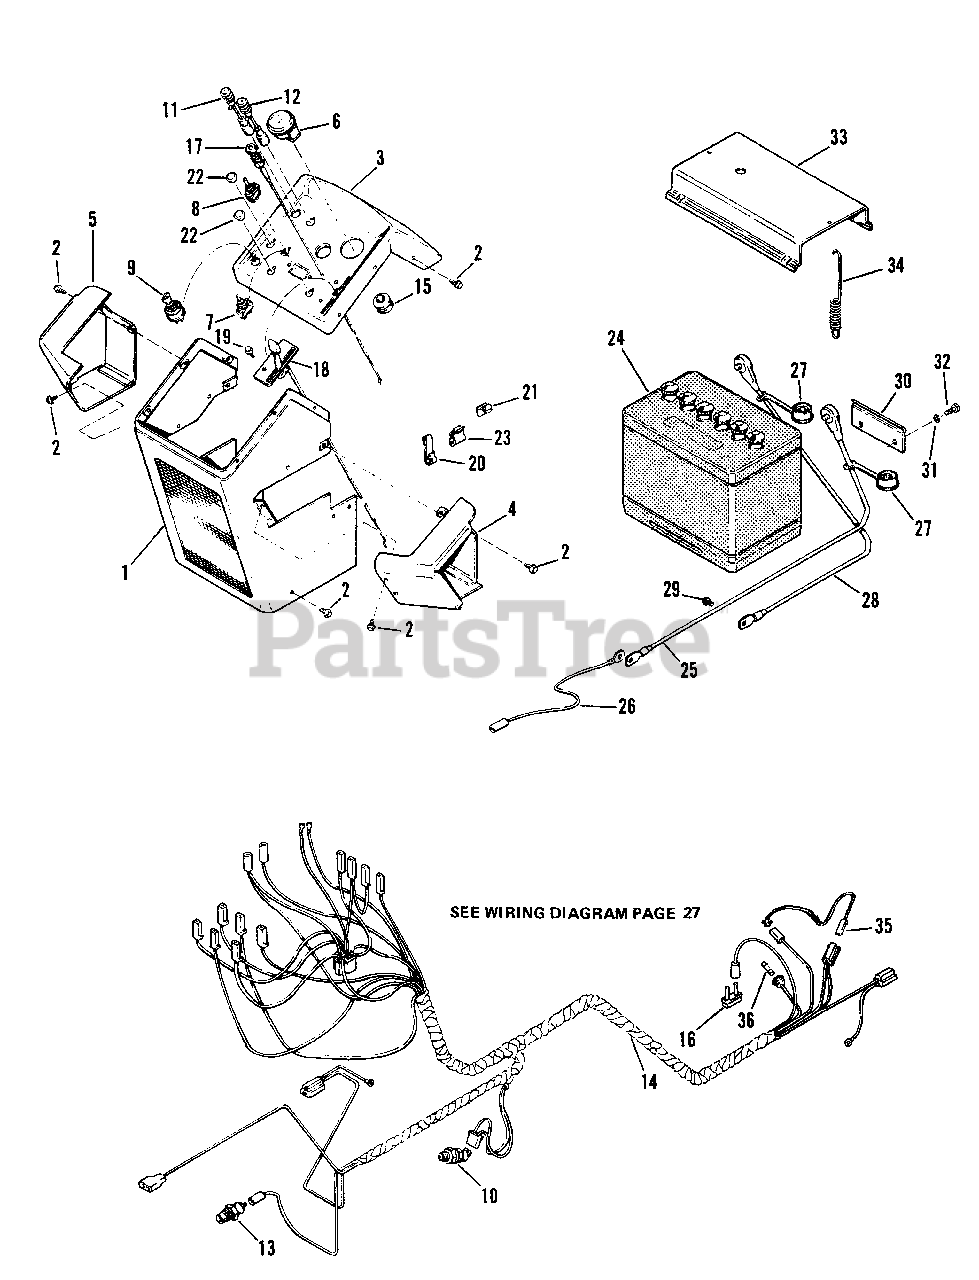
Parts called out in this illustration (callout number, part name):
1	Body Support Assembly
2	Thread Forming Screw, 1/4"-20 x 3/8" lg.
3	Panel Assembly
4	Panel Assembly, R.H.
5	Panel Assembly, L.H.
7	Electric Switch
8	Toggle Switch
9	Ignition Switch
10	Safety Switch
11	Indicator Light, Hot
12	Indicator Light, Oil
13	Indicator Light Switch
14	Wiring Harness
16	Circuit Breaker
17	Choke Control
18	Throttle Control
19	Thread Forming Screw 1/4"-20 x 5/8" lg.
21	Speed Clip
22	Plug Button
24	Battery
25	Cable-Positive
28	Cable-Negative
29	Taptite Screw, 5/16"-18 x 3/8" lg.
31	Hex Capscrew, 5/16"-18 x 3/4" lg.
32	Lock Washer, 5/16"
36	Fuse, 30 Amps.
